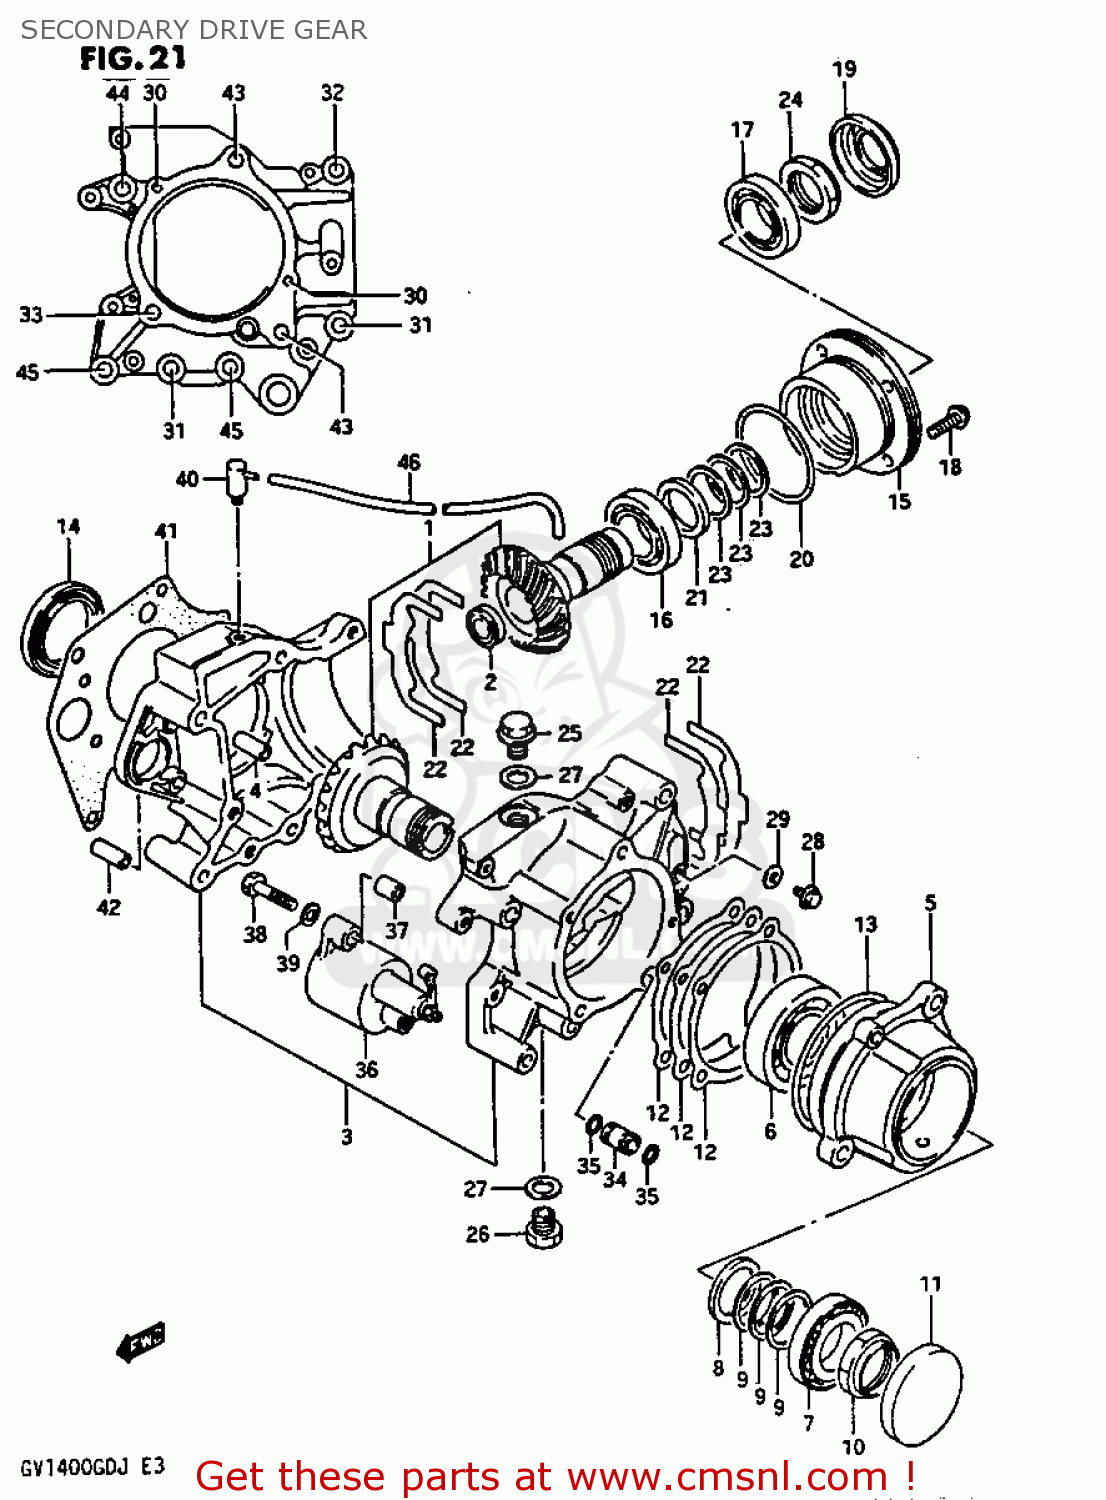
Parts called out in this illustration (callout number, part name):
1	GEAR SET,SECONDARY
2	PLUG
3	CASE ASSEMBLY,SECONDARY
4	PIN (11X20)(SUS)
5	HOUSING,SECONDARY DRIVE BEARING
6	TAPER,ROLLER BEARING
7	BEARING(32X58X17)
8	SPACER(32.4X40X3)
9	SHIM(32X38X2)
10	NUT,SECONDARY DRIVE BELT
11	PLUG
12	SHIM,SECONDARY DRIVE
13	O RING(D:3,ID:78)
14	SEAL,OIL(48X62X6)
15	HOUSING,SECONDARY DRIVEN BEVEL
16	BEARING(35X62X18)
17	BEARING(32X58X17)
18	BOLT
19	SEAL,OIL(29.5X60X17.5)
20	O RING(D:3.1,ID:69.4)
21	SPACER
22	SHIM,SECONDARY DRIVEN HOUSING
23	SHIM(32X38X2)
24	NUT
25	PLUG(14X12)
26	PLUG
27	GASKET(14X19.2X2) (NAS)
28	BOLT
29	GASKET(5.8X13X1.2) (NAS)
30	BOLT 6X25
31	BOLT 8X60
32	BOLT (8X70)
33	BOLT(8X95)
34	PIN,OIL GALLERY
35	O RING(D:1.9,ID:9.8)
36	CYLINDER,CLUTCH RELEASE
37	PIN
38	BOLT ,6X35
39	WASHER,LOCK
40	BPLUG,BEVEL GEAR BREATHER
41	GASKET,SECONDARY GEAR CASE (NAS)
42	PIN(10.4X13X22)
43	BOLT
44	BOLT
45	BOLT(8X110)
46	HOSE
